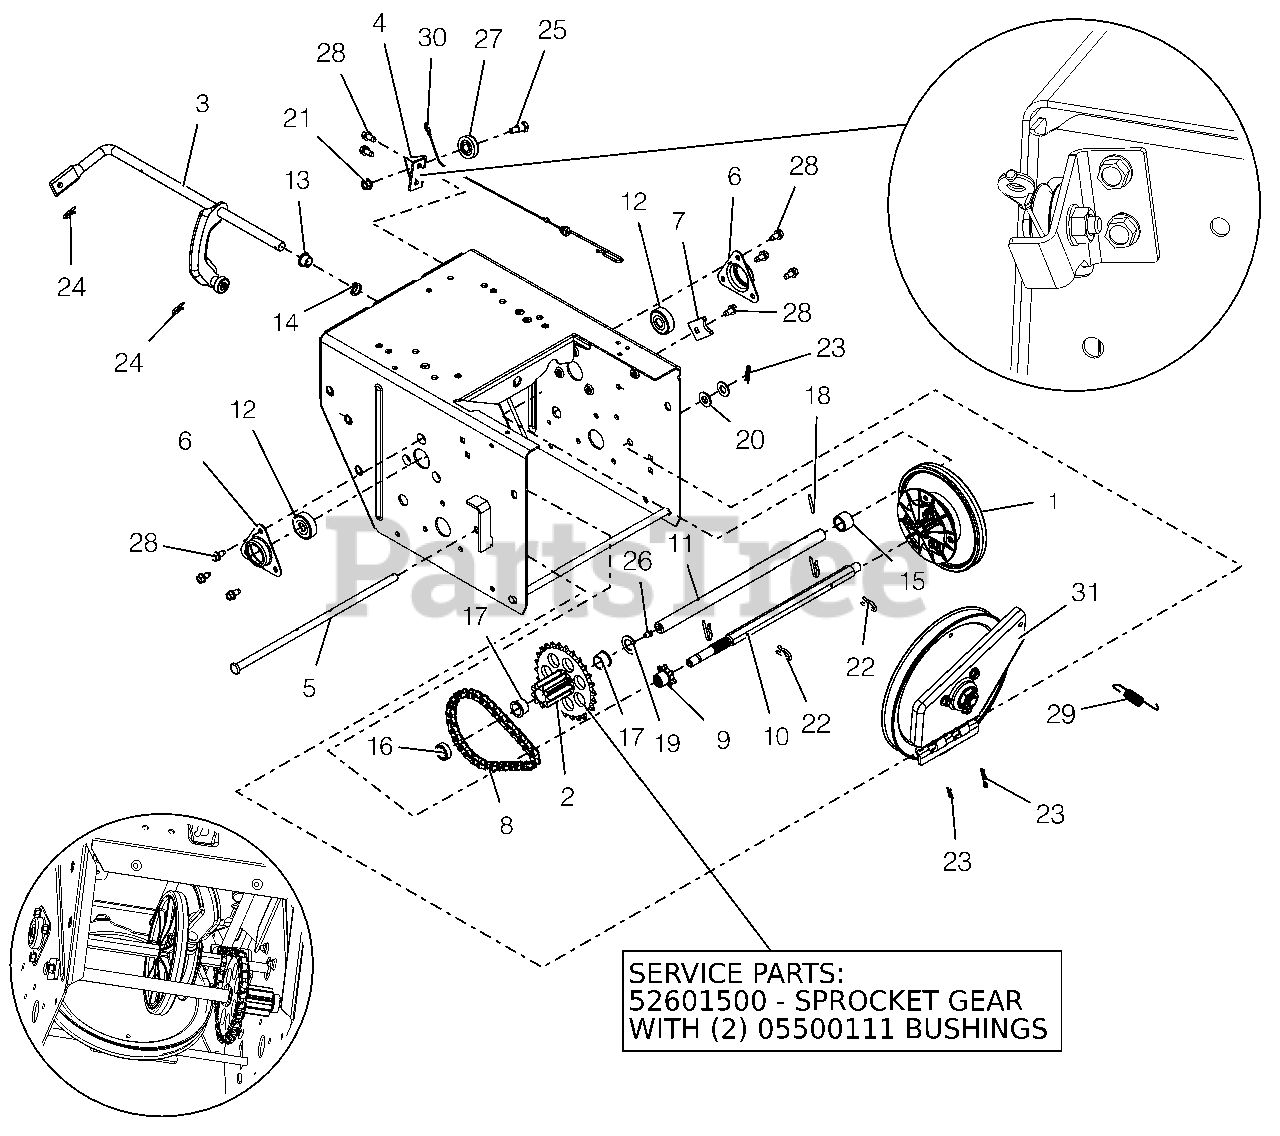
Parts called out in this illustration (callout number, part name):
1	DISC, FRICTION DRIVE-ASSEMBLY
2	PINION & SPROCKET
2	PINION & SPROCKET W/BUSHINGS
2	BSHG-FLG .625X.750X.500X.875
3	ARM, SHIFT-PRO (ASSEMBLY)
4	BRACKET, CABLE PULLEY
5	PIN, PIVOT
6	FLANGE, BEARING
7	TAB, ANTI ROTATION
8	CHAIN - #41, 32 PITCHES
9	SPROCKET, PINION 7T W/SPLINE
10	SHAFT, HEX - HEAT TREATED
11	SHAFT, PINION - HARDENED
12	BRG-BALL .437X1.375X.437
13	BUSHING, POLYLINER-.50 SPLIT
14	BUSHING, POLYLINER-.50 SNAPIN
15	SPACER, .635X.880X.611
16	BSHG-SLV, .635X.880X.305
17	BSHG-FLG .625X.750X.500X.875
18	PIN-ROLL .125X1.00
19	WSHR-FL-STL .630X1.005X.062 YZ
20	@WSHR-FL-STL.406X.812X.065 YWZ
21	@NUT-LK-TOP-FLG .25-20 YWZC
22	PIN, SPRING CLIP
23	PIN-HAIR, ENDRIES #25 YWZC
24	CLIP, SPRING
25	BOLT, SHLDR-.375X.375X.25-20
26	ZERK,FITTING .25X.125 DRIVE IN
27	PULLEY, CABLE
28	SCR-TAP .25-20X.50 HWH TR YWZ
29	SG-TENS .048X.50X2.8
30	CABLE, LOWER TRACTION,SS & PRO
31	PLATE, SWING ASSEMBLY-DEEP
